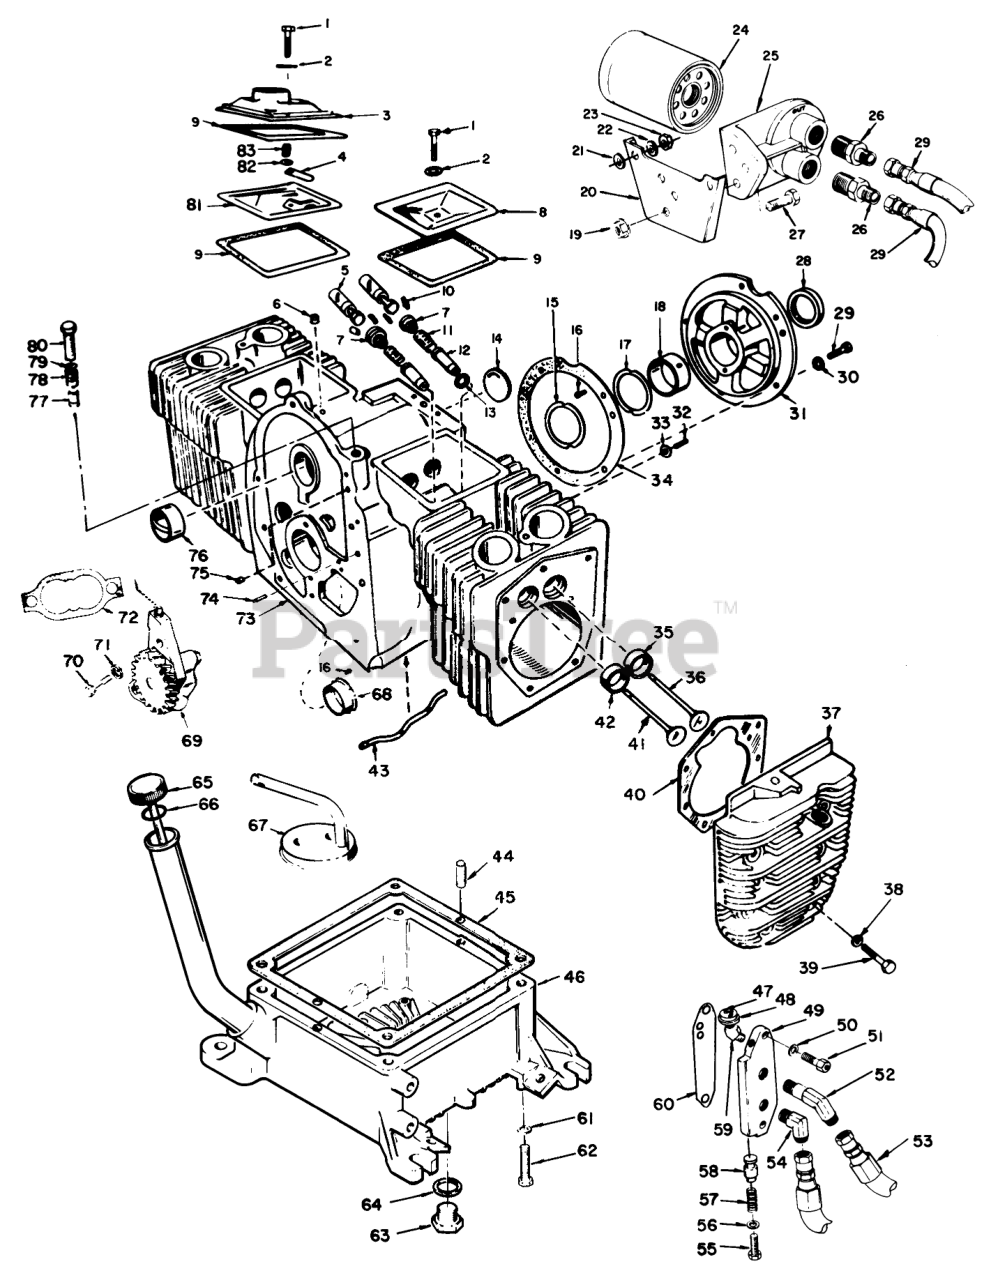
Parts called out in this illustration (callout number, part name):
1	SCREW-HH
2	WASHER
3	VALVE COVER
4	VALVE
5	TAPPET
6	PLUG-BREATHER HOLE
7	ROTOCAP
8	VALVE COVER
9	GASKET
10	LOCK (SET OF 2)
11	SPRING
12	GUIDE
13	GASKET
15	WASHER
16	PIN-DRIVE
18	Bearing, Crankshaft Rear Standard (Incl. Ref. #15)
19	SELF LOCKNUT
20	BRACKET
21	OIL SEAL
22	WASHER
23	NUT-HEX
24	FILTER-OIL
25	BASE ASM
26	MALE CONNECTOR
27	SCREW-HH
29	HEX HD CAPSCREW
30	WASHER-LOCK
31	Plate-Bearing
33	WASHER
34	GASKET
35	STD INSERT
36	VALVE
37	CYL RS HEAD
38	WASHER
39	HEX HD CAPSCREW
40	GASKET
41	EXHAUST VALVE
42	STD INSERT
43	OIL TUBE
44	DOWEL PIN
45	GASKET
46	OIL BASE ASM
48	SWITCH
49	Adapter,Oil Filter
50	WASHER
51	HEX SOCKET CAPSCREW
52	MALE CONNECTOR
53	FLEX HOSE ASM
54	MALE CONNECTOR
55	SCREW-HH
56	WASHER
57	Spring, Bypass
58	PLUNGER
59	ELBOW-45 DEG
60	Gasket
61	WASHER-LOCK
62	SCREW-HH
63	PLUG-OIL
64	GASKET
65	INDICATOR & CAP
66	SEAL 0-RING
67	OIL CUP ASM
68	KIT-BEARING, SLEEVE
70	SCREW-HH
71	WASHER-LOCK
72	GASKET KIT
73	Block Assy. (Incl. Ref. #6,12-18, 29-31, 34-35, 42, 43, 68, 74 & 76)
74	PIN-GEAR COVER
75	PLUG-CORE HOLE
76	SLEEVE-BEARING
77	PLUNGER
78	SPRING
79	WASHER
80	SCREW-HH
81	BAFFLE
82	WASHER-FLAT
83	SPRING
